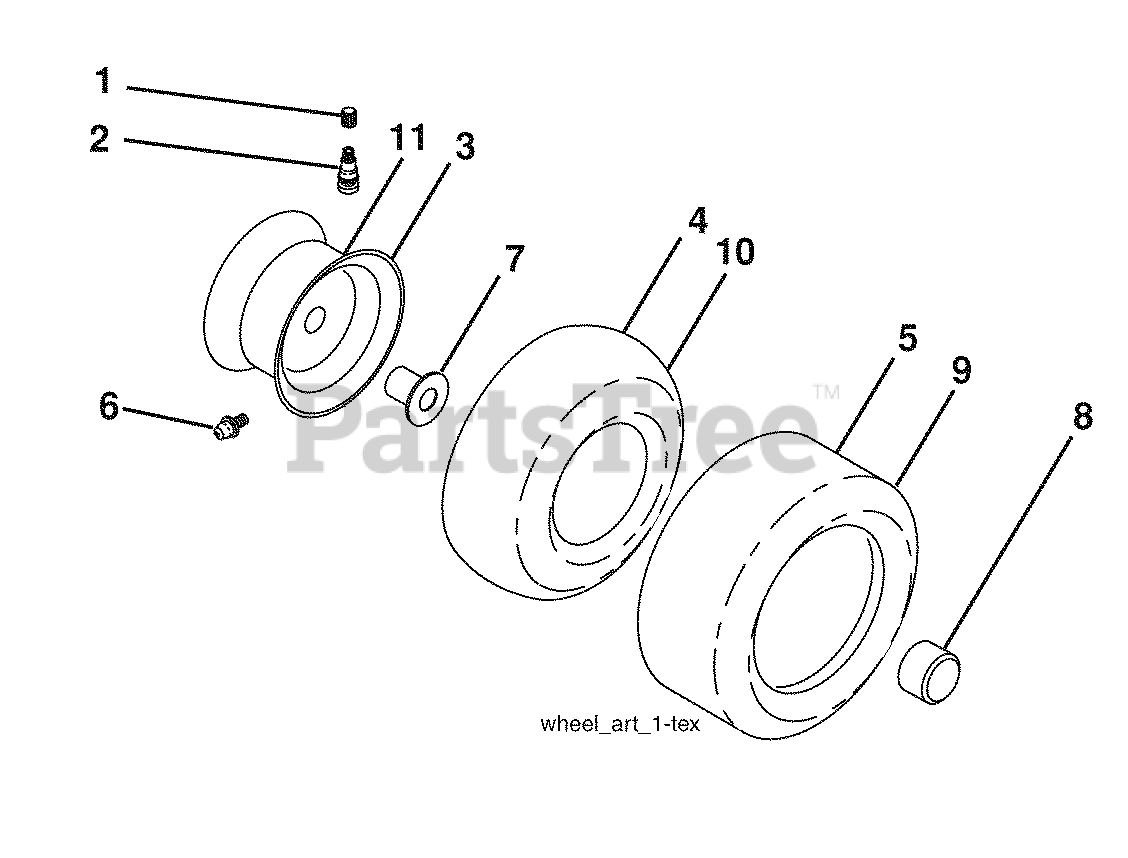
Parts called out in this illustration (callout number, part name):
1	Cap Valve Tire
2	Stem Valve
3	Rim Front
4	Tube Front
5	Tire Front 15 x 6.0-6
6	Fitting Grease
7	Bearing Flange
8	Cap Axle Blk 1 50 x 1 00
9	Tire R 18 x 9.5-8 Turf Saver LT
10	Tube Rear
11	Rim Asm 8" Rear
